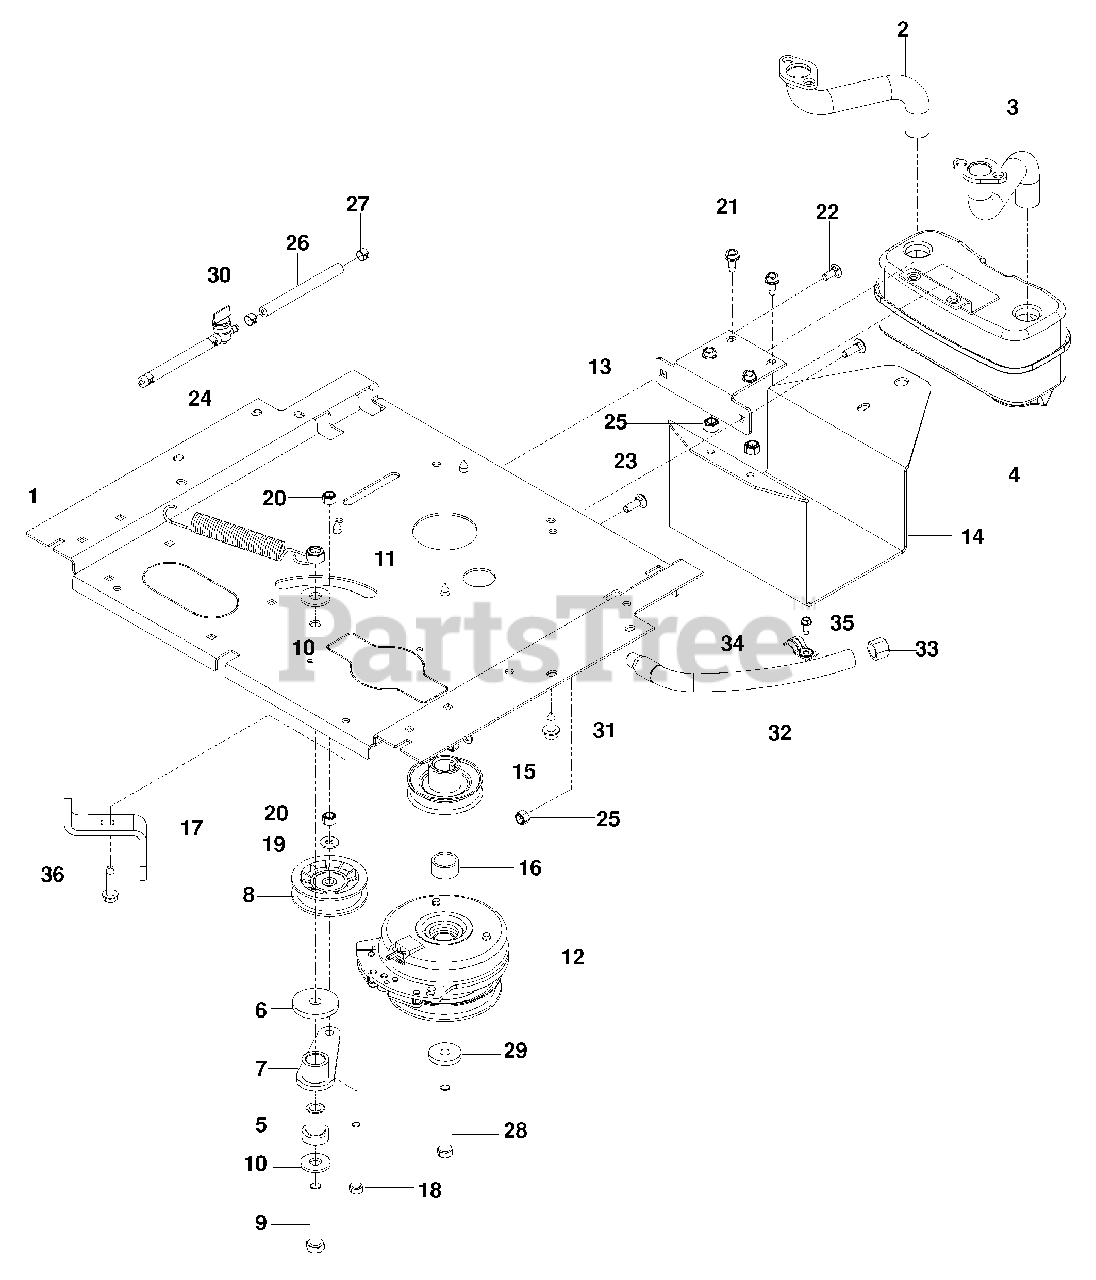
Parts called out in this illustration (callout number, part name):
1	Plate, Engine Blk
2	Exhaust Tube, Rt
3	Exhaust Tube, Lt
4	Muffler Asm Twin
5	Spindle, Idler
6	Washer, Heavy
7	Arm, Idler
8	Pulley, Idler
9	Hcs 1/2-13 X 3 1/4
10	Washer 1/2 Flat
11	Nut 1/2 Hex Nyloc
12	Clutch, 105 Ft/Lbs
13	Bracket, Muffler Blk
14	Guard, Muffler Blk
15	Pulley, Engine
17	Stop, Clutch
18	Hcs 3/8-16 X 3 1/2 Tpblt
19	Washer 5/16 Std Flat
20	Nut 3/8-16 Hex Nyloc
21	Bolt 5/16-18 X 3/4 Thd Frm
22	Rhsnb 5/16-18 X 3/4
23	Rhsnb 5/16-18 X 1
24	Spring, Deck Drive
25	Nut 5/16-18 Flange Nyloc
26	Fuel Line 5"
27	Clamp, Hose
28	Hcs 7/16-20 X 3 1/2
29	Washer, Clutch
30	Valve, Fuel
31	Hhfs 3/8-16 X 1 Thd Frm
32	Hose, Drain
35	Screw 1/4-20 X 5/8 Slf Tap
36	Bolt 3/8-16 X 1 1/2 Thd Frm
